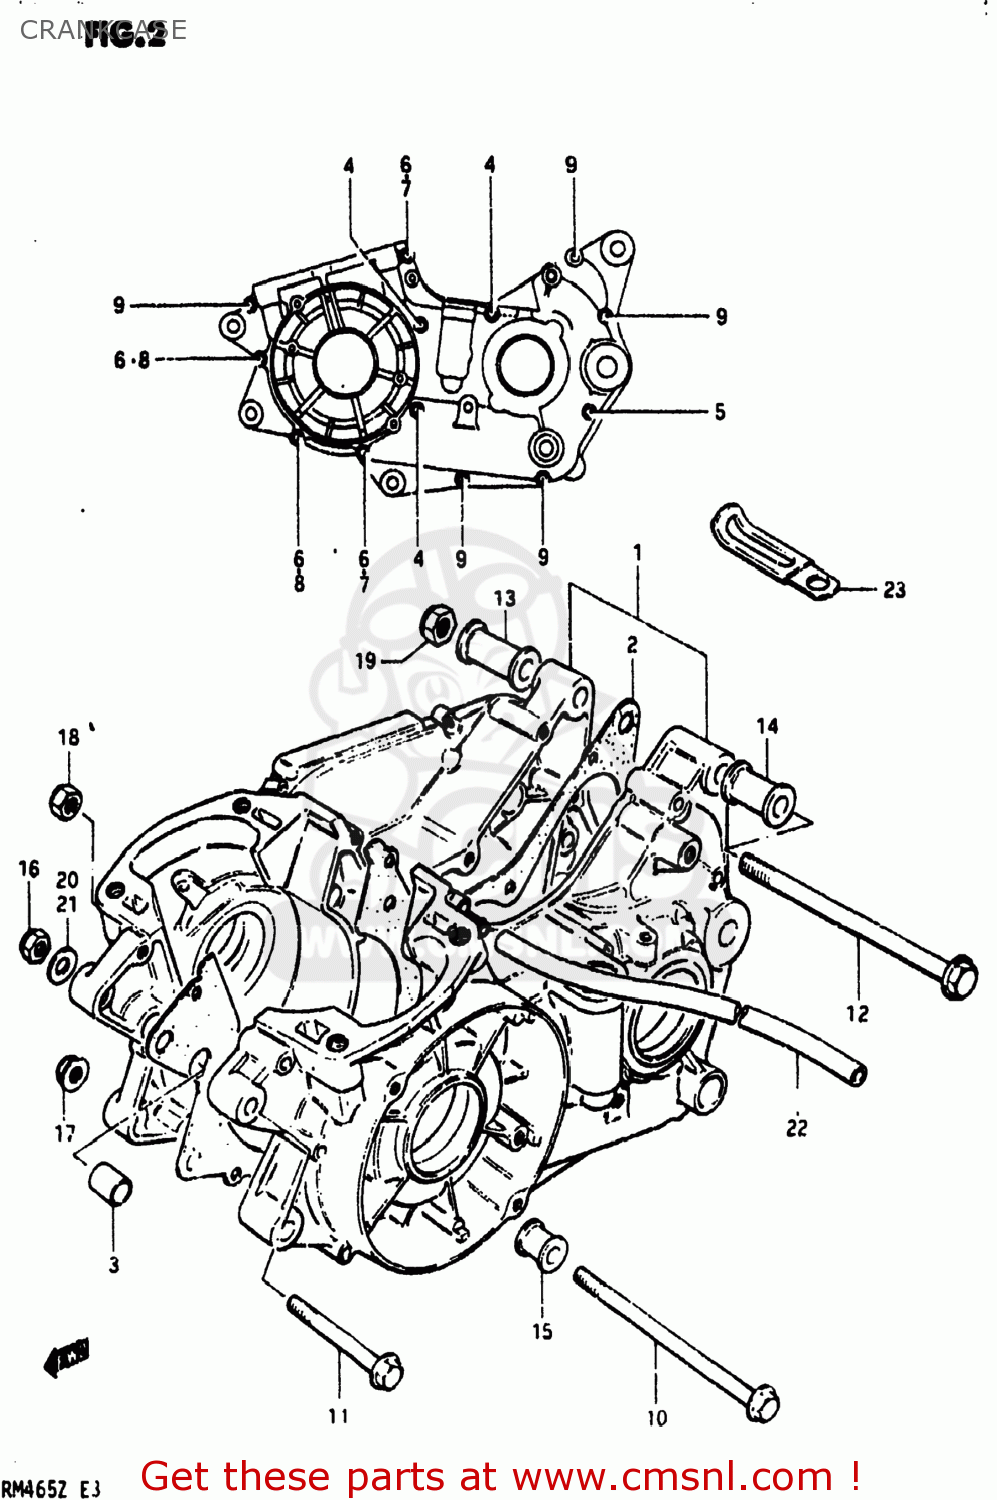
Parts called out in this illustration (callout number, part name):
1	CRANKCASE SET
2	GASKET,CRANKCASE (MCA)
3	PIN
4	SCREW 6X65
5	SCREW
6	SCREW (6X45)
7	SCREW (6X45)
8	SCREW
9	SCREW (6X35)
10	BOLT
11	BOLT(8X75)
12	BOLT 10X215
13	SPACER,ENGINE MOUNT
14	SPACER,ENGINE MOUNT
15	SPACER,ENGINE MOUNT
16	NUT
17	NUT
18	NUT
19	NUT
20	WASHER
21	WASHER
22	HOSE
23	CLAMP
